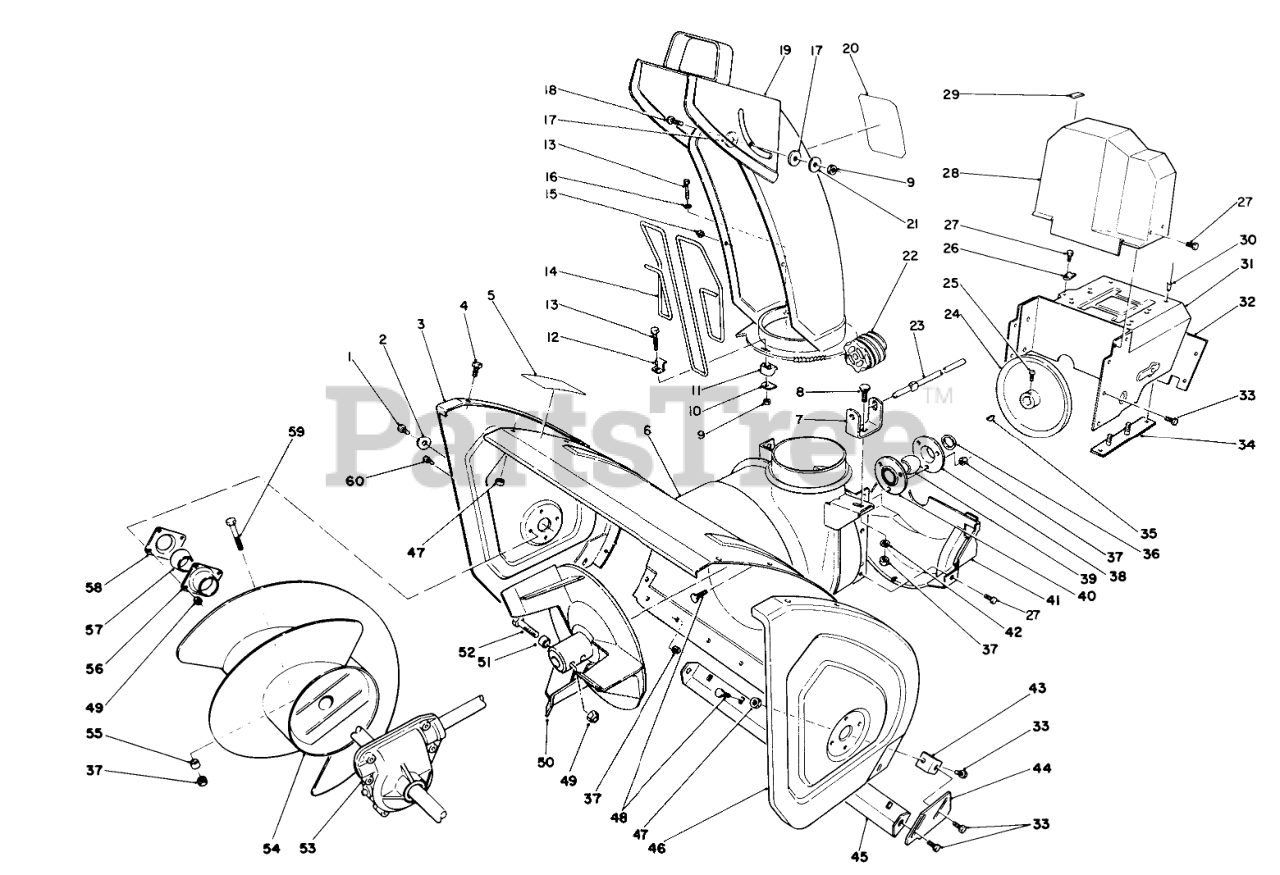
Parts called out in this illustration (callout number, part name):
1	SCREW-HH
2	WASHER
3	PLATE-SIDE, RH
4	SCREW-HHF
5	DECAL-WARNING, AUGER
6	Housing-28"
7	BRACKET-WORM, CHUTE
8	BOLT-CARR
9	NUT-LOCK, NI
10	PLATE-RETAINER, CHUTE
11	RETAINER-CHUTE
12	CLIP-GUARD, CHUTE
13	SCREW-HSH
14	GUARD-CHUTE
15	NUT-PUSH
16	WASHER-FLAT
17	WASHER-PLASTIC
19	Assembly
20	Decal-Danger
21	WASHER-FLAT
22	GEAR-WORM
23	ROD-CHUTE, LOWER
24	PULLEY-IMPELLER
25	SCREW-SET, SQH
26	RETAINER-CABLE
27	SCREW-HWH
28	COVER-BELT, UPPER
29	COVER-CABLE
30	RIVET-POP
31	Frame-Engine
32	Cover-Frame, Engine
33	SCREW-HHF
34	PLATE ASM FRM LH 11 B&S
35	KEY-WOODRUFF
36	WASHER-THRUST
37	NUT-LOCK, NI
38	Flange-Bearing (Rear)
39	BEARING-BALL
40	Flange-Bearing (Front)
41	Cover-Belt (Lower)
42	WASHER-PLAIN
43	Bracket-Skid
44	Plate-Skid LH
45	Blade-Scraper
46	Plate-Side LH
47	NUT-LOCK, NI
48	SCREW-CARR
49	NUT-LOCK, NI
50	Impeller
51	SPACER
52	SCREW-HHF
53	Auger Gearbox Assembly
54	Auger-R.H.
55	SPACER-HUB, AUGER
56	BEARING-FLANGE, FRONT
57	BEARING
58	BEARING-FLANGE, REAR
59	Auger Bolt
60	SCREW-HH
